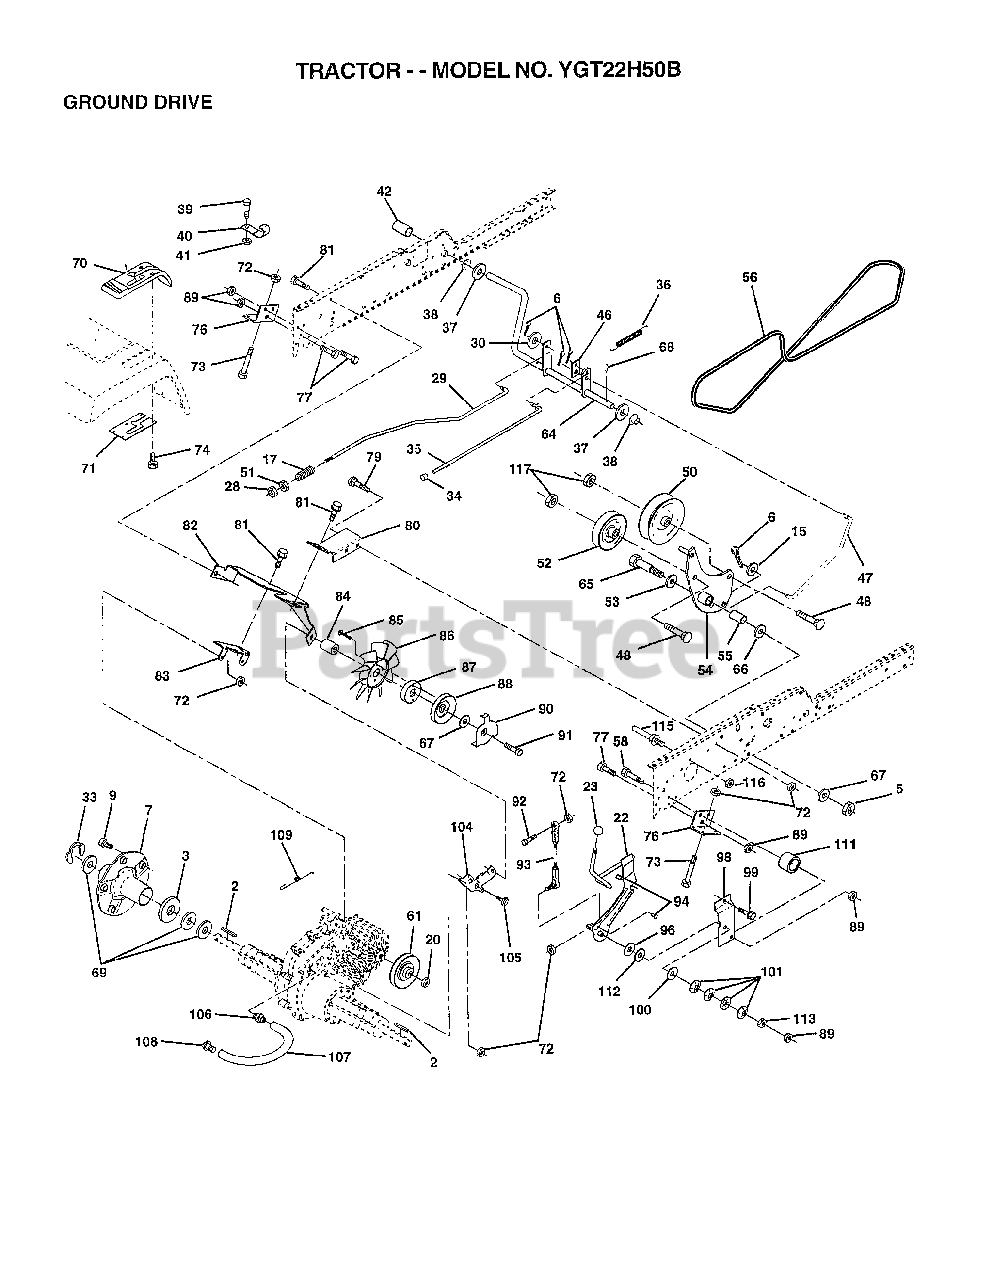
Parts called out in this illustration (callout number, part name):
2	KEY 1/4 X 2.5
3	WASHER T
6	COTTER PIN
7	HUB WHEEL ASM
9	BOLT.HUB.WHL.REAR
15	WASHER
17	SPRING ROD BRAKE
22	ARM ASM SHIFT
23	KNOB DLX BLK/BLK
28	NUT
29	ROD BRAKE
30	WASHER HYT
33	E RING HYT
34	PLUNGER CAP T
35	ROD BRAKE PART GT
36	SPRING.GRND.DRIVE
38	BUSHING.NYLINER
39	SCREW
40	ACT-SWITCH T
42	"COVER,PEDAL"
46	RETAINER.SPRING
47	ROD.CLUTCH
48	BOLT.3/8-16X1.50
50	FLAT IDLER PULLEY
52	PULLEY.IDLER.V.GR
53	WASHER T
54	CLUTCH.ARM.ASM
55	"LY, BEARING"
56	BELT-V 84.5
58	BOLT
61	PULLEY TRANSAXLE
64	SHAFT-BRAKE/CLUTC
65	AXLE BOLT
66	WASHER.HARD.BLADE
67	WASHER
68	ROLL PIN STD
69	WASHER
71	"PLATE CONSOLE,SFT"
72	NUT
73	BOLT.HEX.FLGHD.
74	SCREW HEXWSH H-L
76	BRACKET TRAN VGTH
77	BOLT
79	BOLT
80	BRACKET TORQUE RH
81	SCREW
82	BRACKET.MTG.FAN
83	STRAP TORQUE MID
84	SPACER
85	SCREW YTV
86	"FAN 7"" HYDRO"
87	ADAPTER FAN
88	PULLEY FAN
89	NUT GTV
90	KEEPER BELT
91	SCREW.HXWSH.3/8
93	LINK ASM SHIFT
94	XMAS TREE FASTNER
96	WASHER NICKEL PLT
98	BRACKET SHIFT
99	SCREW LT
100	WASHER COMPRESSIN
101	WASHER-BELLVILLE
104	BRACKET IDLER
105	SCREW CRT
106	O-RING.ASM.70110
107	"LINE FUEL,HYD 15"""
108	CAP.VENT.70109
109	SPRING BRAKE
111	"SPACER-LEVER,SHIF"
112	"WASHER-NYLON,HIGH"
113	NUT
115	"KEEPER,DRIVE BELT"
116	"NUT HEX,LOCK,FLAN"
